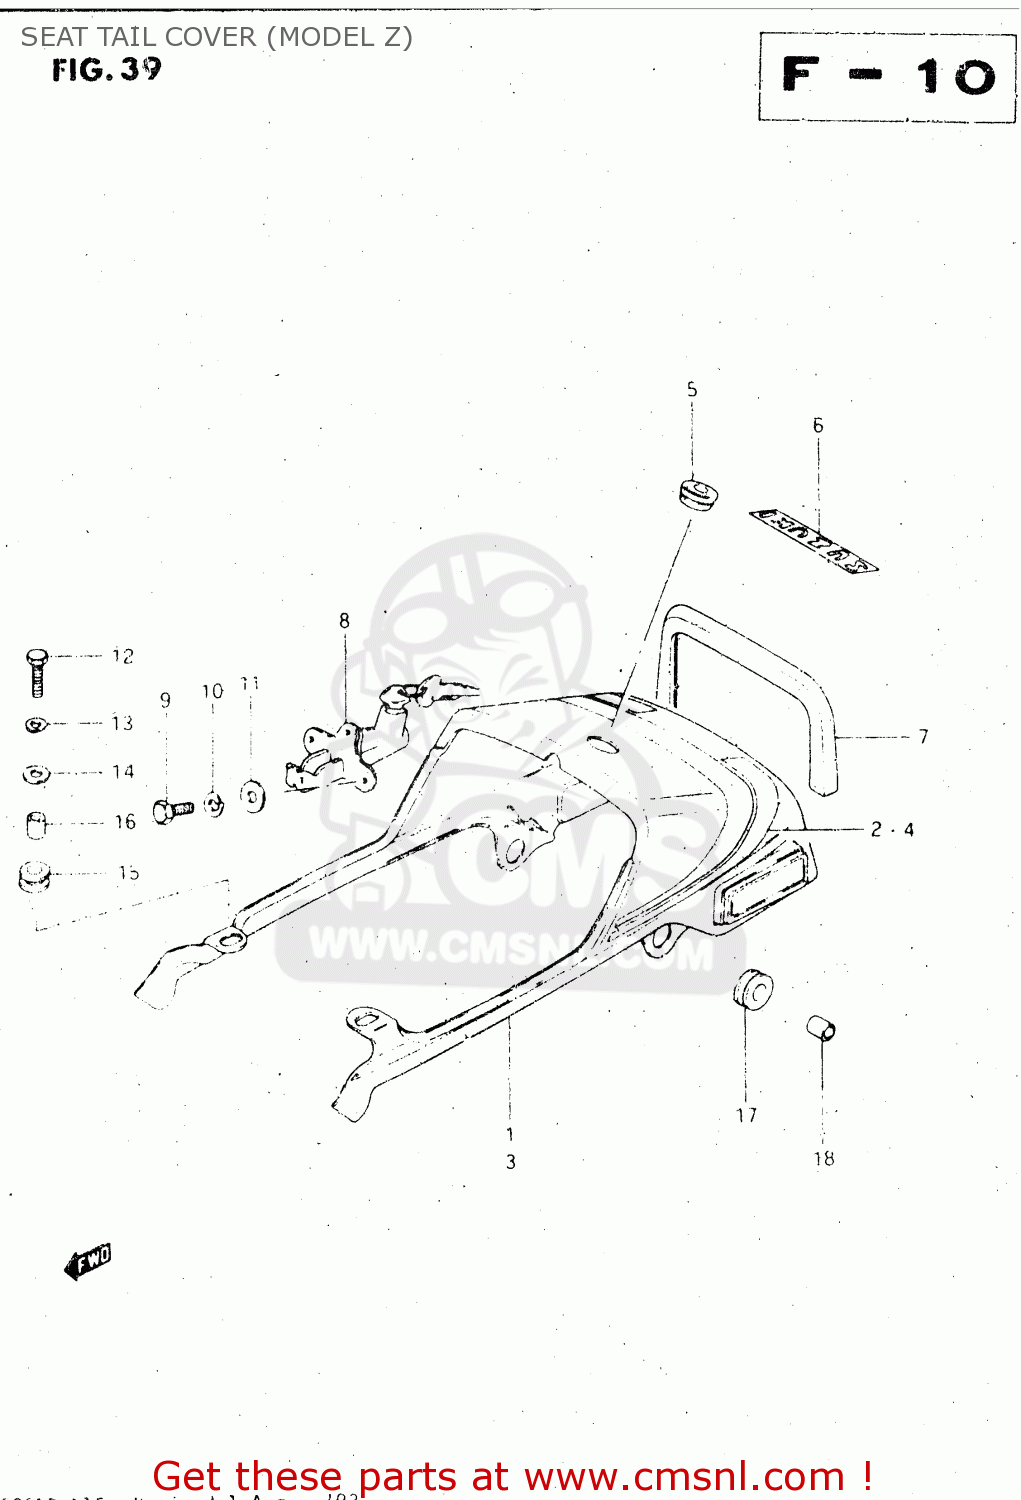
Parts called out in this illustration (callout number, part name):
1	COVER, SEAT TAIL (RED)
2	TAPE SET
3	COVER,SEAT TAI
4	TAPE SET
5	GROMMET,SEAT LOCK HOLE
6	EMBLEM,SEAT TAIL COVER
7	GROMMET
8	LOCK SET,SEAT
9	BOLT
10	LOCK WASHER
11	WASHER
12	BOLT
13	LOCK WASHER
14	WASHER(6,5X22X1.6)
15	CUSHION
16	SPACER(6.5X10.5X12)
17	CUSHION
18	SPACER
